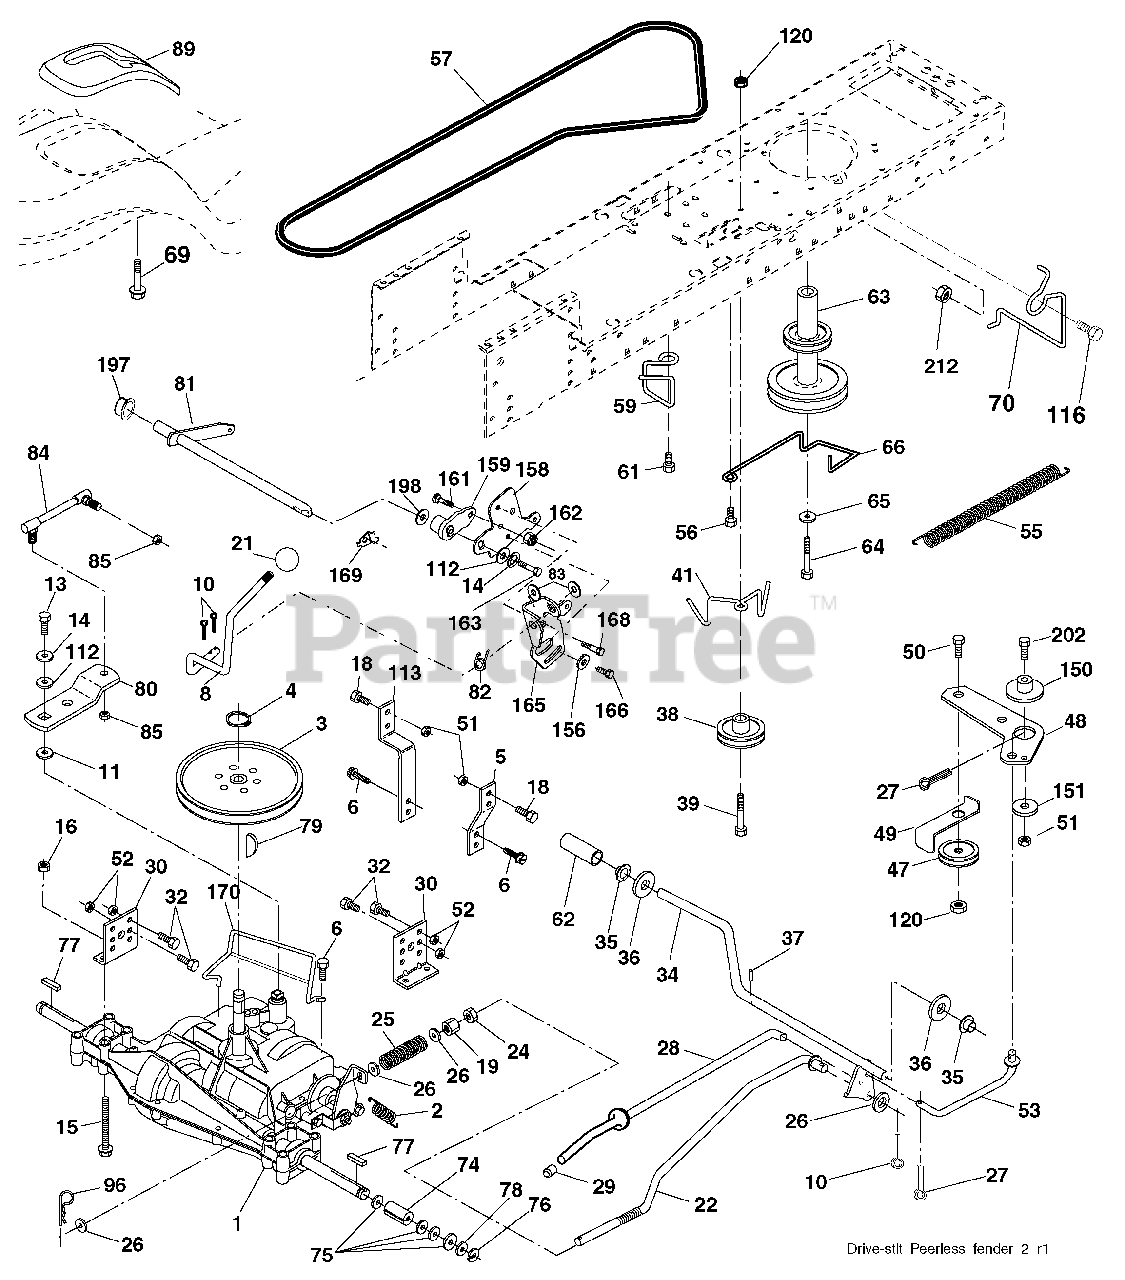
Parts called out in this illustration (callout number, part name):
2	Spring Return Brake
3	Pulley Transaxle 18"Tires
4	Ring Retainer # 5100-62
5	Strap Torque 30 Degrees RH
6	Screw 5/16-18 x 3/4
8	Rod Shifter Blk
10	Pin Cotter 1/8 x 1 Cad
11	Washer Plate Shf 388 Sq Hole
13	Bolt 1/4-28 unf Gr. 8 w/Patch
14	Washer Lock Hvy Helical 1/4
15	Bolt Hex Flghd 5/16-18 Gr. 5
16	Nut 5/16-18
18	Bolt Fin Hex 3/8-16 unc x 1 Gr.
19	Nut lock Hex w/Ins 3/8-16 unc
21	Knob
22	Rod Brake LT
24	Nut Hex Jam 3/8-16 unc
25	Spring Rod Brake 2 00 Zinc
26	Washer 13/32 x 13/16 x 16 Ga.
27	Pin Cotter 1/8 x 3/4 Cad
28	Rod Brake Parking LT/YT
29	Cap Brake Parking Black
30	Bracket Transmission
32	Bolt Fin Hex 5/16-18 x 3/4
34	Shaft Asm Pedal Foot Nibbed
35	Bearing Nylon Blk 629 Id
36	Washer 21/32 x 1 x 16 Ga.
37	Pin Roll 3/16 x 1"
38	Pulley Composite Flat
39	Bolt 3/8-16 x 2-3/4
41	Keeper Belt Idler
47	Pulley Idler V Groove Plastic
48	Bellcrank Clutch Grnd Drv STL
49	Retainer Belt Style Spring
50	Bolt Carr Sh 3/8-16 x 1-1/2 Gr.
51	Nut Crownlock 3/8-16 unc
52	Nut Crownlock 5/16-18 unc
53	Link Clutch
55	Spring Return Clutch 6 75
56	Screw 3/8-16 x 1-1/4
57	V-Belt Ground Drive 95.68
59	Keeper Belt Chassis Span Ctr
61	Screw 3/8-16 x .875
62	Cover Pedal Blk Round
63	Engine Pulley LT/YT
64	Bolt Hex 7/16-20 x 4 Gr. 5
65	Washer Lock Hvy Hlcl Spr 7/16
66	Keeper Belt Engine
69	Screw 1/4 x 1/2 unc
70	Guide Belt Mower Drive RH
74	Spacer Axle
75	Washer 25/32 x 1 1/4 x 16 Ga.
76	E-ring #5133-75
77	Key Square 2 0 x 1845/ 1865
78	Washer 25/32 x 1-5/8 x 16 Ga.
79	Key Woodruff
80	Arm Shift Transaxle
81	Shaft Asm Cross Taper
82	Spring Torsion Shift
83	Washer 17/32 x 3/4 x 16 Ga.
84	Link Transaxle
85	Nut Lock Center 1/4-28
89	Console Shift
96	Retainer Spring 1"
112	Washer 9/32 x 3/4 x 10 Ga.
113	Strap Torque 90 Degrees LH
116	Bolt Rdhd Sq Neck 3/8-16 x 1
120	Nut Lock Flg 3/8-16
150	Spacer Retainer Lt
151	Washer 13/32 x 2 x 10 Ga.
156	Washer Srrrtd 5/16 ID x 1.0 x .125
158	Bracket Shift Mount
159	Hub Shift
161	Bolt 1/4-20 x 3/4 Gr. 5
162	Nut Crownlock 1/4-20 unc
163	Bolt Hex Fin 1/4-20 unc x 1 Gr. 5
165	Bracket Pivot Lever
166	Screw 5/16-18 x 5/8
168	Bolt Shoulder 5/16-18 x .561
169	Plate Fastening
170	Keeper, Belt Transaxle
197	Nyliner Snap-In 5/8
198	Washer Nylon
202	Bolt Carr Sh 3/8-16 x 1-3/4 Gr. 5
212	Nut Hex Flg Lock
